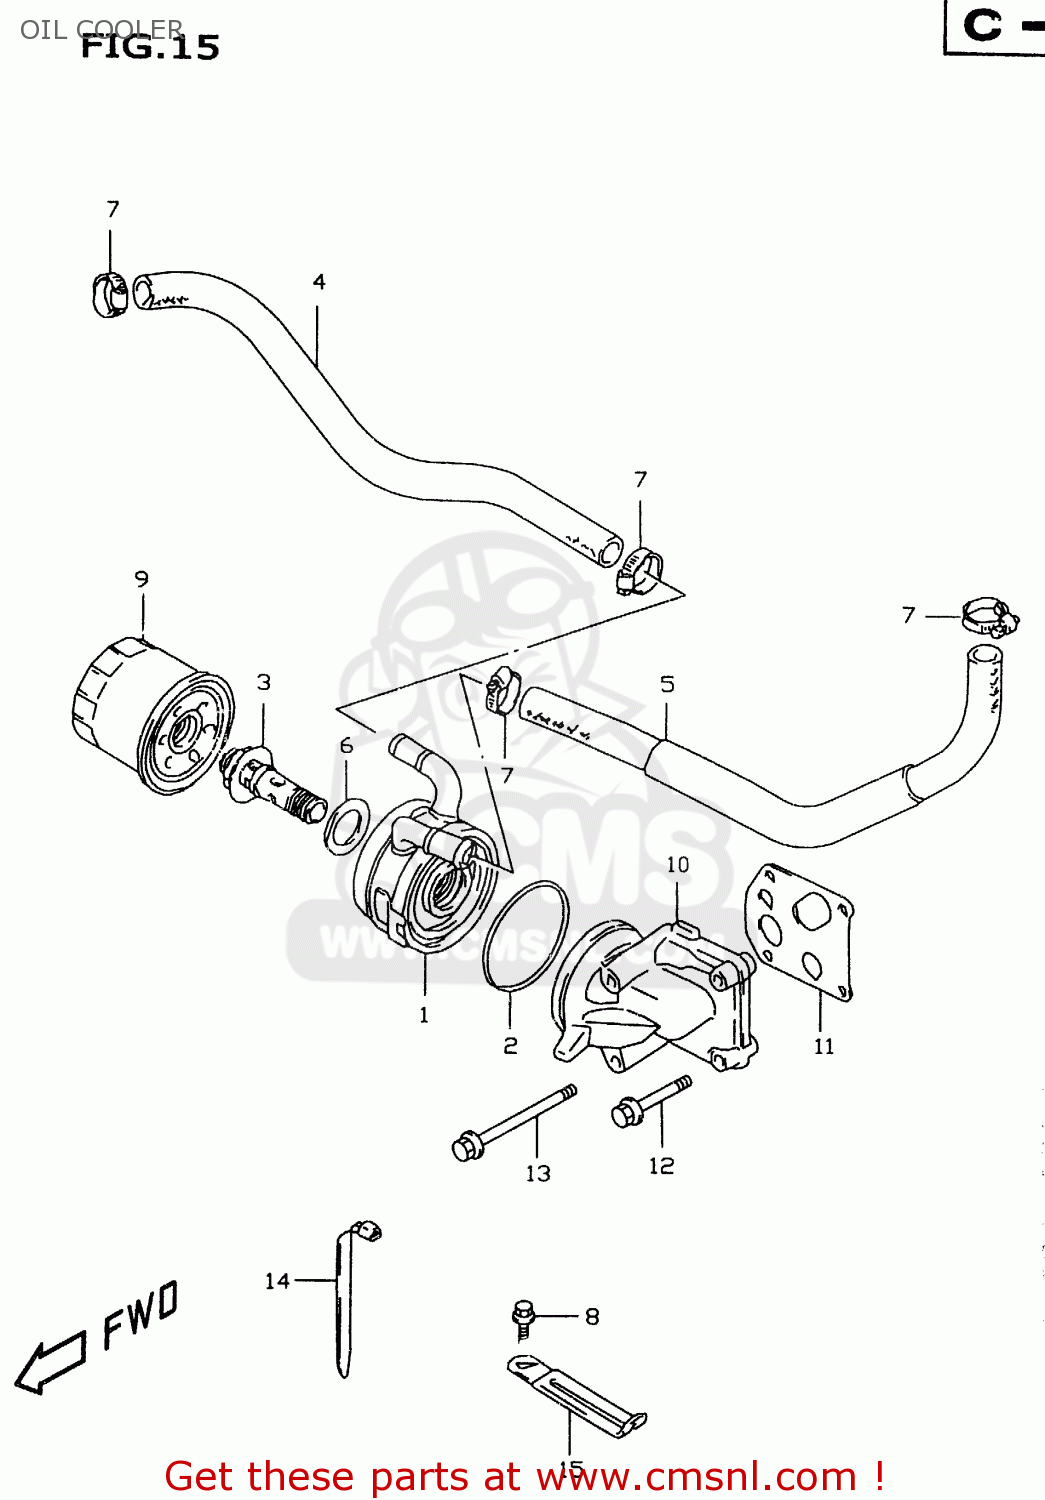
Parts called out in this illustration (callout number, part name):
1	COOLER ASSEMBLY,OIL
2	O RING(D:3.1,ID:63.9)
3	BOLT,OIL COOLER UNION
4	HOSE,OIL COOLER WATER IN
5	HOSE,OIL COOLER WATER OUT
6	SHIM
7	CLAMP
8	BOLT 6X12
9	FILTER ASSEMBLY,ENGINE OIL
10	HOLDER,OIL FILTER
11	GASKET,OIL FILTER HOLDER
12	BOLT(6X40)
13	BOLT(6X65)
14	CLAMP(L:235)
15	CLAMP(L:80)
